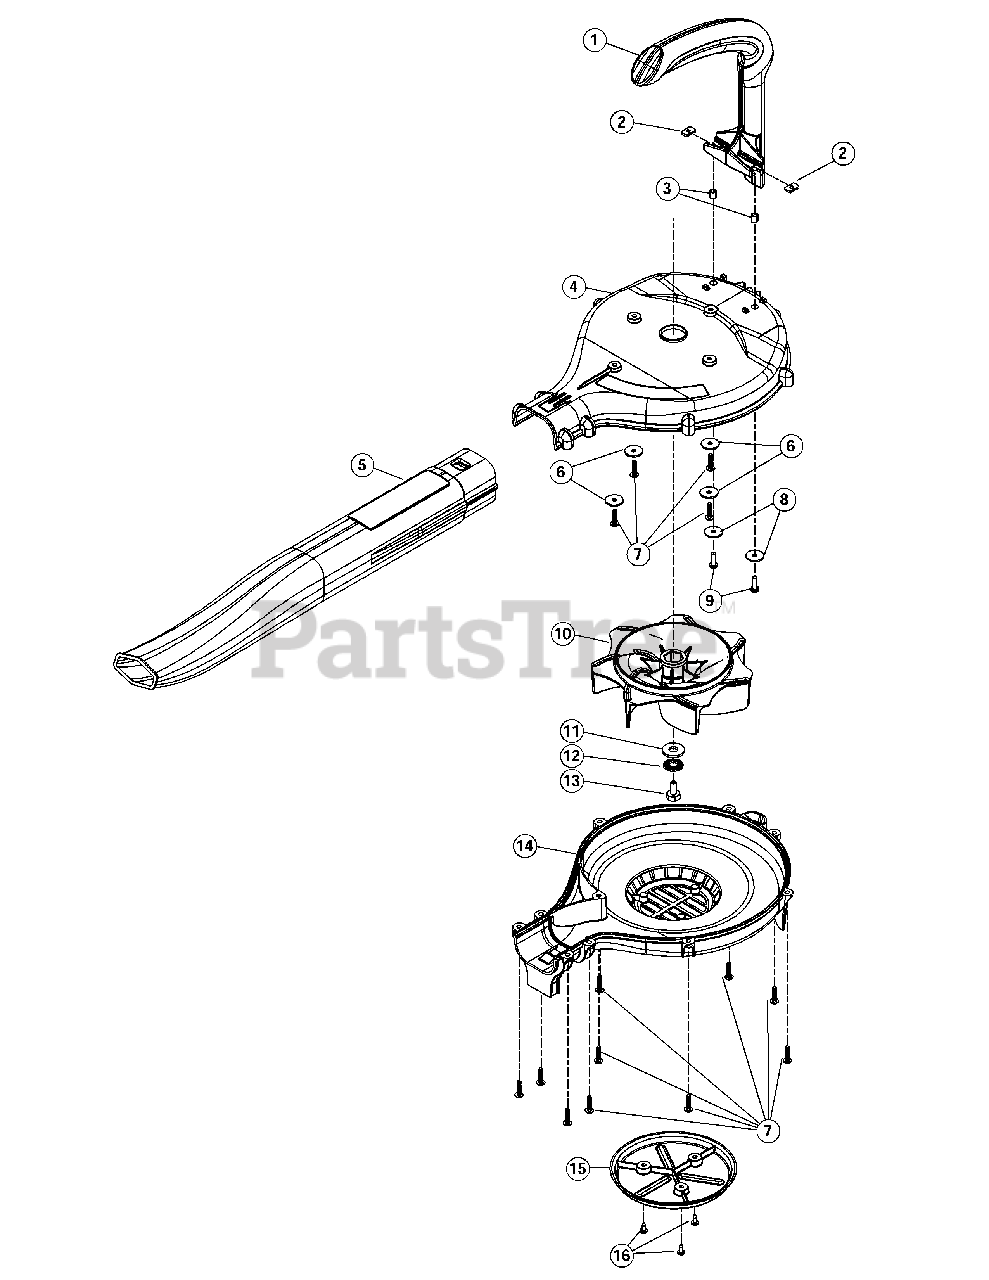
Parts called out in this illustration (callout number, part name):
1	Blower Handle
2	Weldnut
3	Spacer
4	Upper Impeller Housing
5	Blower Tube
7	Housing Screw
8	Handle Washer
9	Handle Screw
10	Impeller
11	Washer
12	Lock Washer
13	Bolt
14	Lower Impeller Housing
15	Intake Deflector
16	Deflector Screw
